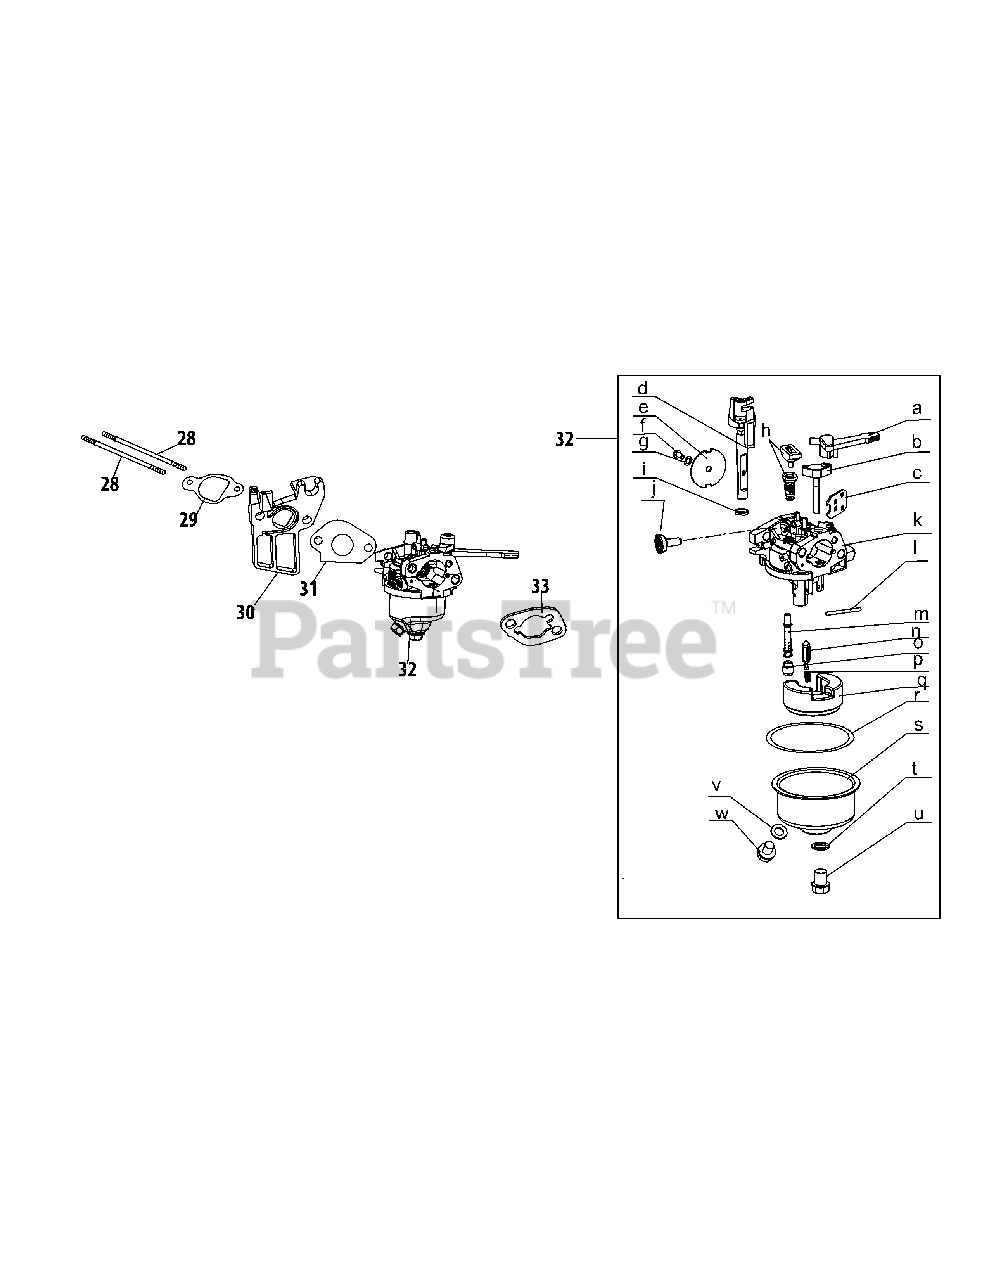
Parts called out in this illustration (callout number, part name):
28	Stud M6×110
29	Carburetor Insulator Gasket
30	Carburetor Insulator
31	Carburetor Gasket
32	Carburetor Assembly
33	Carburetor Gasket Plate
